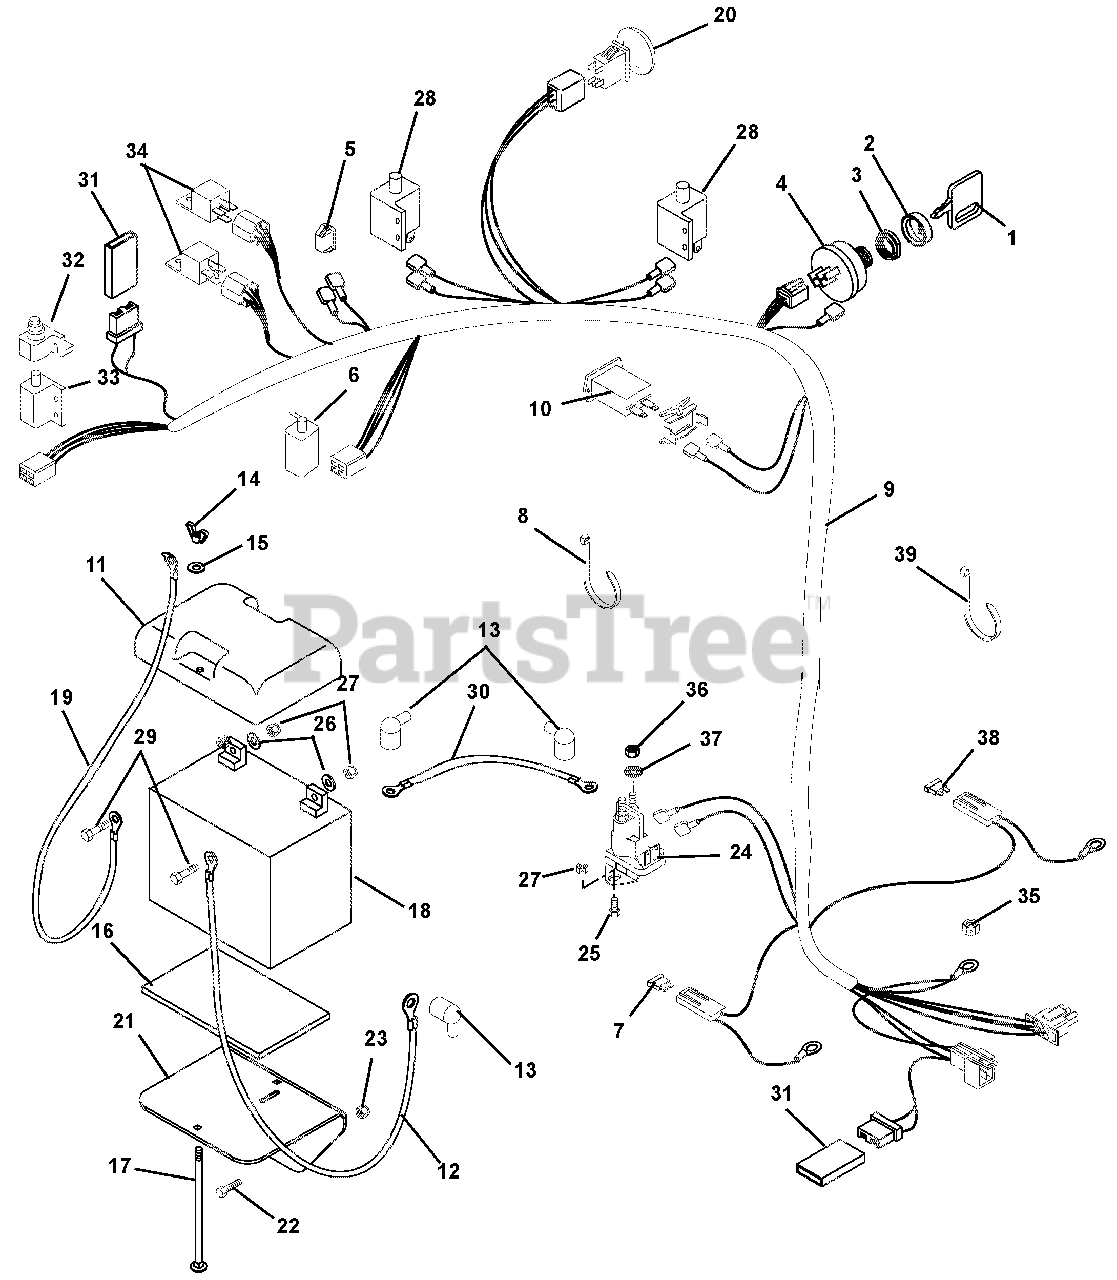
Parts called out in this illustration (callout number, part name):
1	Key- with Cap
2	Cap, Ignition Switch
3	Nut, Panel .625-32
4	Key Switch
5	Light, Indicator
6	Switch- Double Pole N.O./N.O. (108, 123, 126)
7	Fuse-25 AMP
8	Tie Wrap-Black
9	Wire Harness (108, 123, 126)
10	Hour Meter-Quartz
11	Cover-Battery
12	Cable, Positive Battery
13	Boot, Eyelet Terminal
14	Nut-Locking-Wing .25-20
15	Washer-Flat-Steel .281 x .625 x .065
16	Pad, Battery
17	Bolt-Round Head Square Neck .25-20 x 7.50 Grade 2
19	Cable, Negative Battery
20	Switch, Clutch With Retainer
21	Weldment, Battery Tray
22	Bolt-Hex .38-16 x 1.75 Grade 5
23	Nut-Locking-Nylon .38-16
24	Solenoid
25	Bolt-Hex .25-20 x .50 Grade 5
26	Washer-Flat-Steel .281 x .62 x .065
27	Nut-Locking-Flange .25-20
28	Switch- Single Pole (N.O.)
29	Bolt-Hex .25-20 x .75 Grade 5
30	Starter Cable 6.75"
31	Diode-Connector Shell
32	Boot, Rubber
33	Switch, Interlock
34	Relay (108, 123, 126)
35	Nut-Locking-Top-Flange .31-18
36	Nut- Jam .31-24
37	Washer-Locking .31
38	Fuse, 20 AMP
39	Tie Wrap
